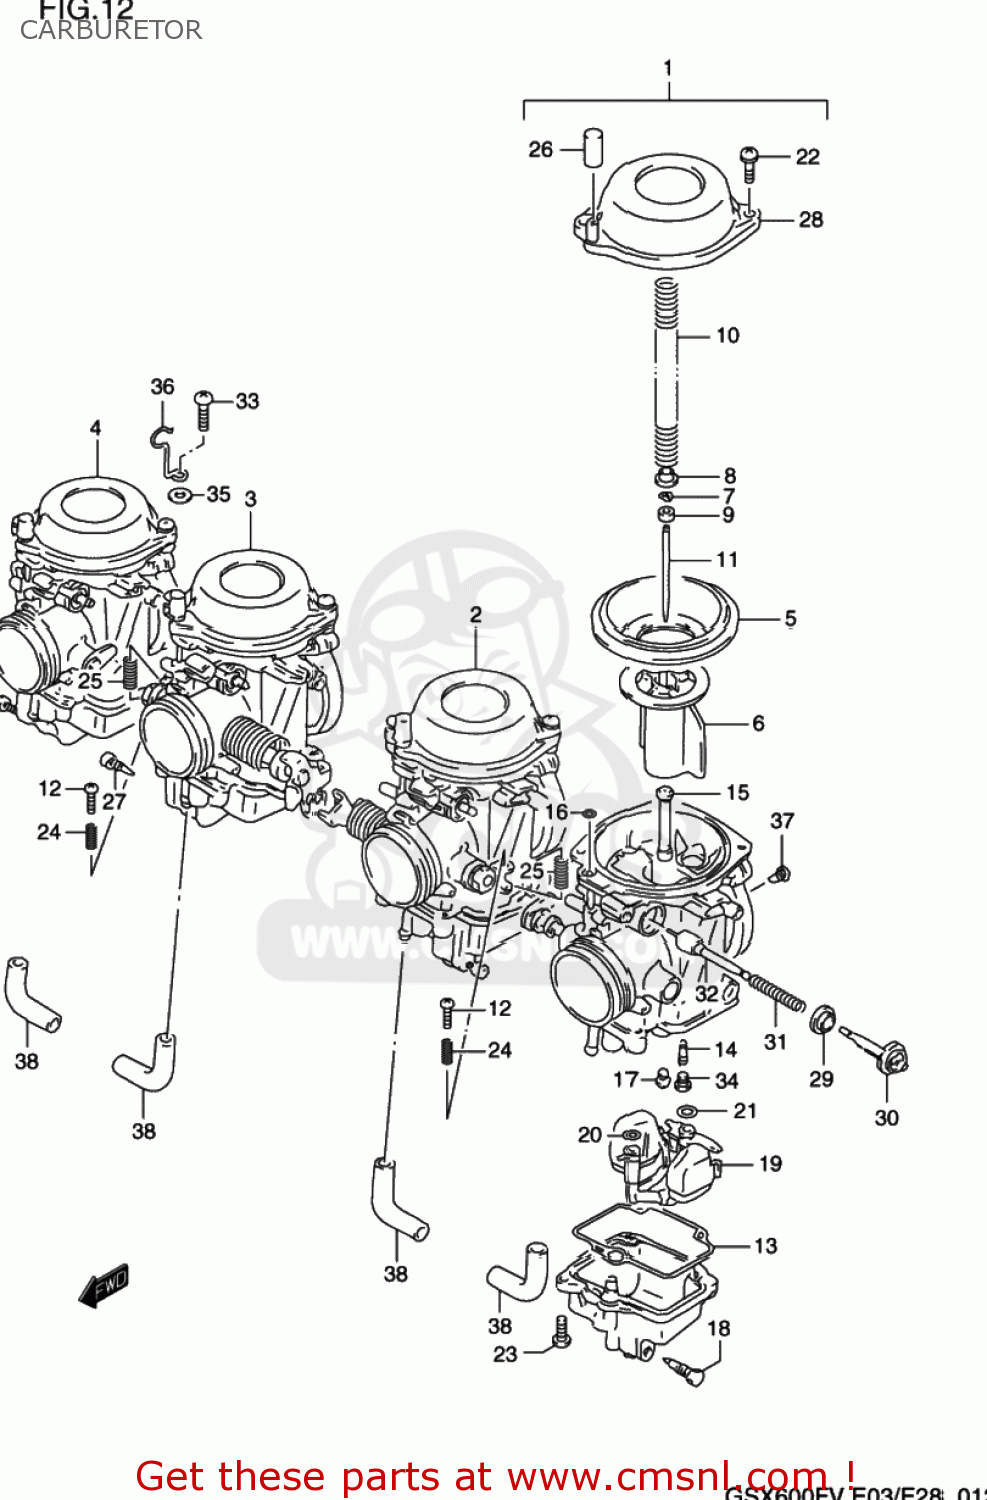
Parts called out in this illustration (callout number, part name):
1	CARBURETOR ASSEMBLY,LEFT
2	CARBURETOR ASSY,ML
3	CARBURETOR ASSY,ML
4	CARBURETOR ASSY,R
5	DIAPHRAGM
6	VALVE,PISTON
7	E RING
8	RING
9	RING
10	SPRING
11	NEEDLE,JET
12	SCREW
13	GASKET,FLOAT CHAMBER (NAS)
14	JET,PILOT(32.5)
15	JET,NEEDLE(P-2M)
16	O RING
17	JET,MAIN(112.5)
18	PLUG,DRAIN
19	FLOAT/NEEDLE VALVE ASSY
20	O RING
21	O-RING,NEEDLE VALVE
22	SCREW
23	SCREW
24	SPRING
25	SPRING
26	CAP
27	SCREW,DRAIN
28	COVER,DIAPHRAGM
29	CAP,STARTER
30	HOLDER,GUIDE
31	SPRING
32	PLUNGER ASSY
33	SCREW
34	PLUG
35	WASHER
36	CLIP
37	JET,AIR(1.55)
38	HOSE
